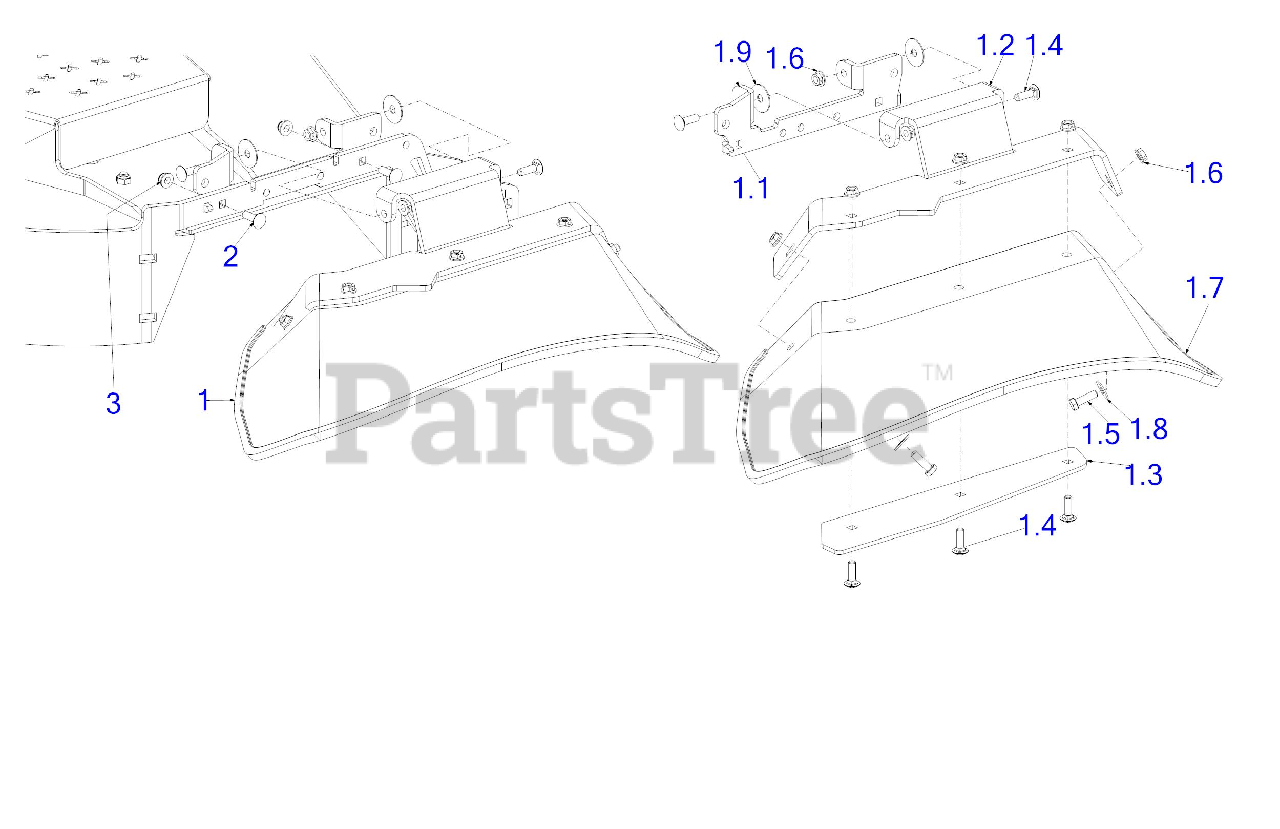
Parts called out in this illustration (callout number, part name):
1	DECK CHUTE ASSEMBLY
1.4	CARRIAGE BOLT 5/16-18 x 1.00
1.5	SCREW 5/16-18 x 1.0 GR5
1.6	HEX FLANGE NUT
1.7	FIBER FORMED CHUTE
1.8	FLAT WASHER
1.9	WASHER .355X1.25X.048THK
2	CARRIAGE BOLT 5/16-18 x 1.00
3	FLANGE LOCK NUT 5/16-18
